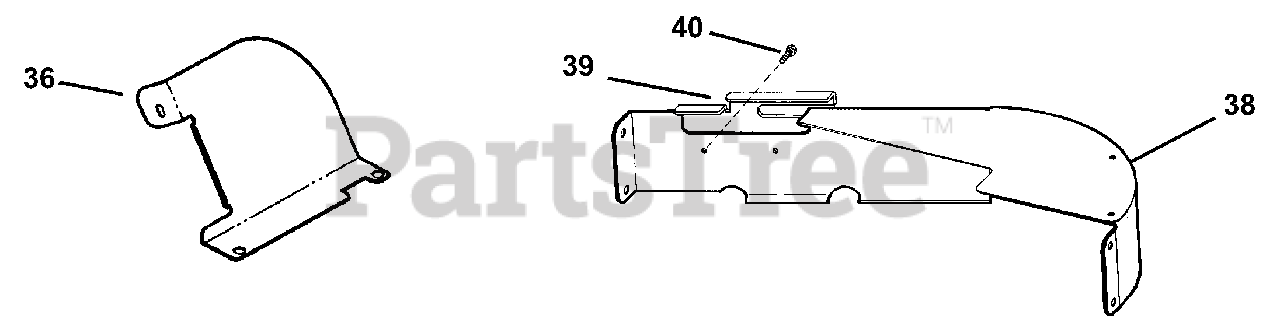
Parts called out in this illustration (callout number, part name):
36	HEAT SHIELD, Starter
38	DUCT, Air (Briggs 18HP)
39	SHIELD, Engine Speed Control Heat
40	SCREW, #10-32 x 3/8" Self Tapping
